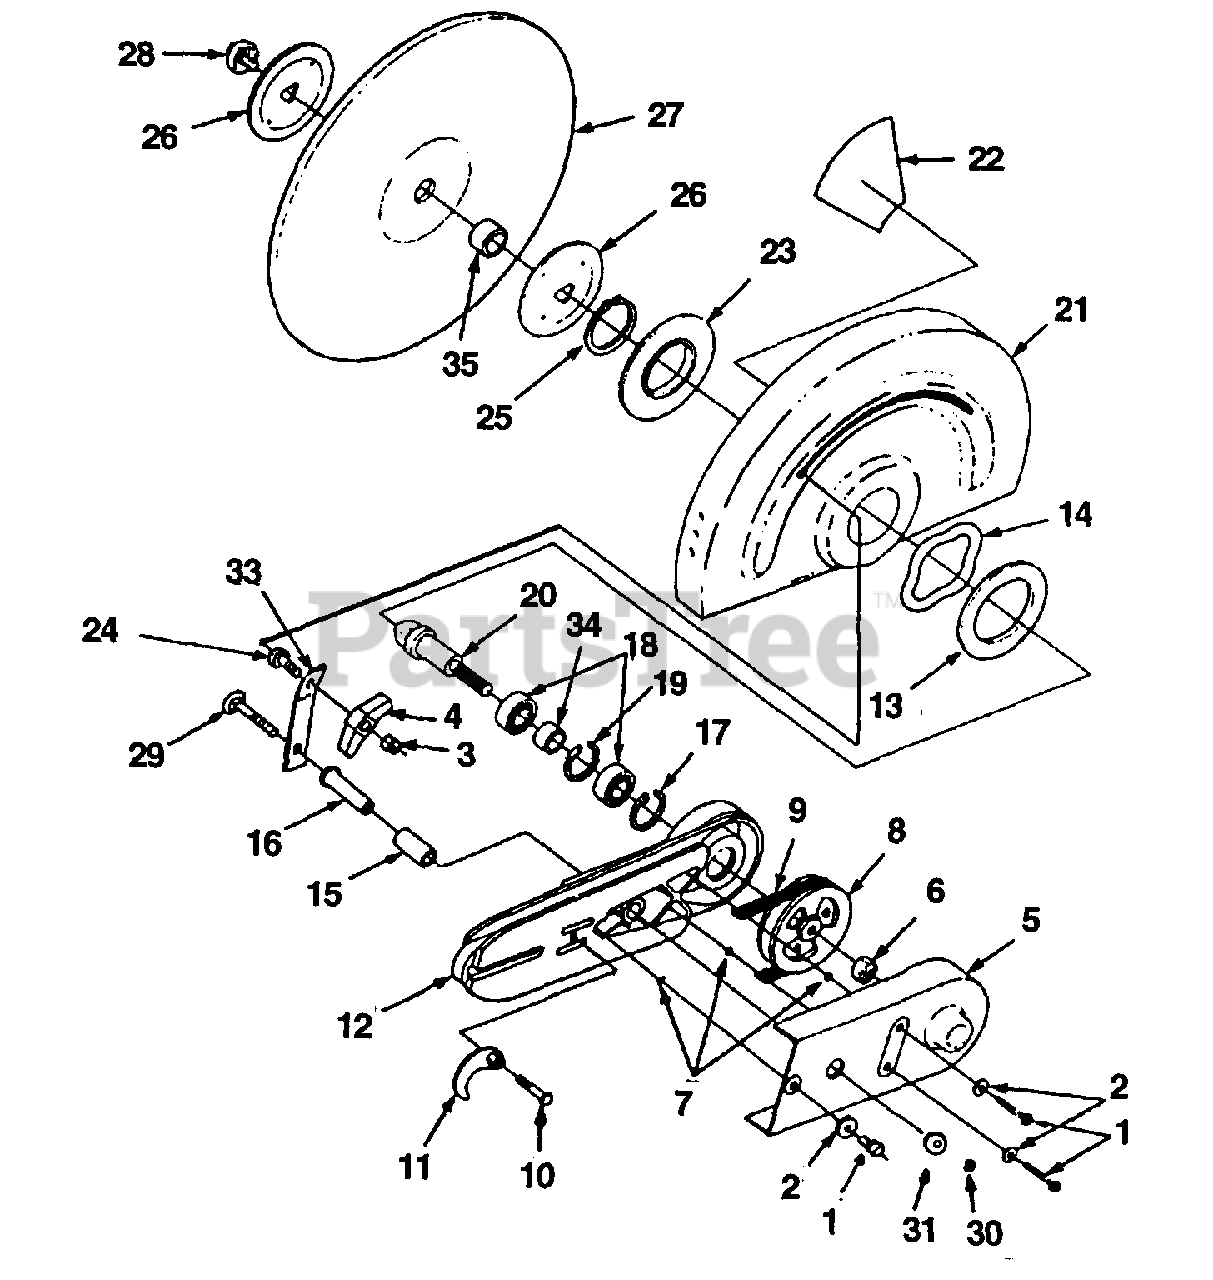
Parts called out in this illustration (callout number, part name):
1	Screw-Slotted
2	Washer-Flat (1/4")
3	Nut-Hex (5/16-18)
4	Knob-Handle
5	Cover-Arm
6	Nut-Hex Lock (1/2-13)
7	"O" Ring
8	Pulley-Driven
9	Belt-"V" Drive
10	Screw-Hex Hd. (5/16-18 X 1 1/2")
11	Cam & Adjuster
12	Arm-Wheel
14	Spring-Wave
15	Tubing-Rubber
16	Spacer-Guard Adjusting
17	Ring-Retaining
18	Ball Bearing
19	Retaining Ring
20	Wheel Shaft
21	Wheel Guard (12" only)
22	Caution Label
23	Washer-Mounting (12" only)
24	Bolt-Step (5/16-18 X 1")
25	Ring-Retaining
26	Flange-Wheel
27	Wheel-Resinoid
28	Bolt & Washer
29	Bolt-Sq. Neck, Rnd. Hd.
30	Nut-Hex (5/16-18)
31	Washer-Flat
33	Arm-Adjusting (12" only)
34	Spacer-Bearing
35	Spacer (1" Dia.)
